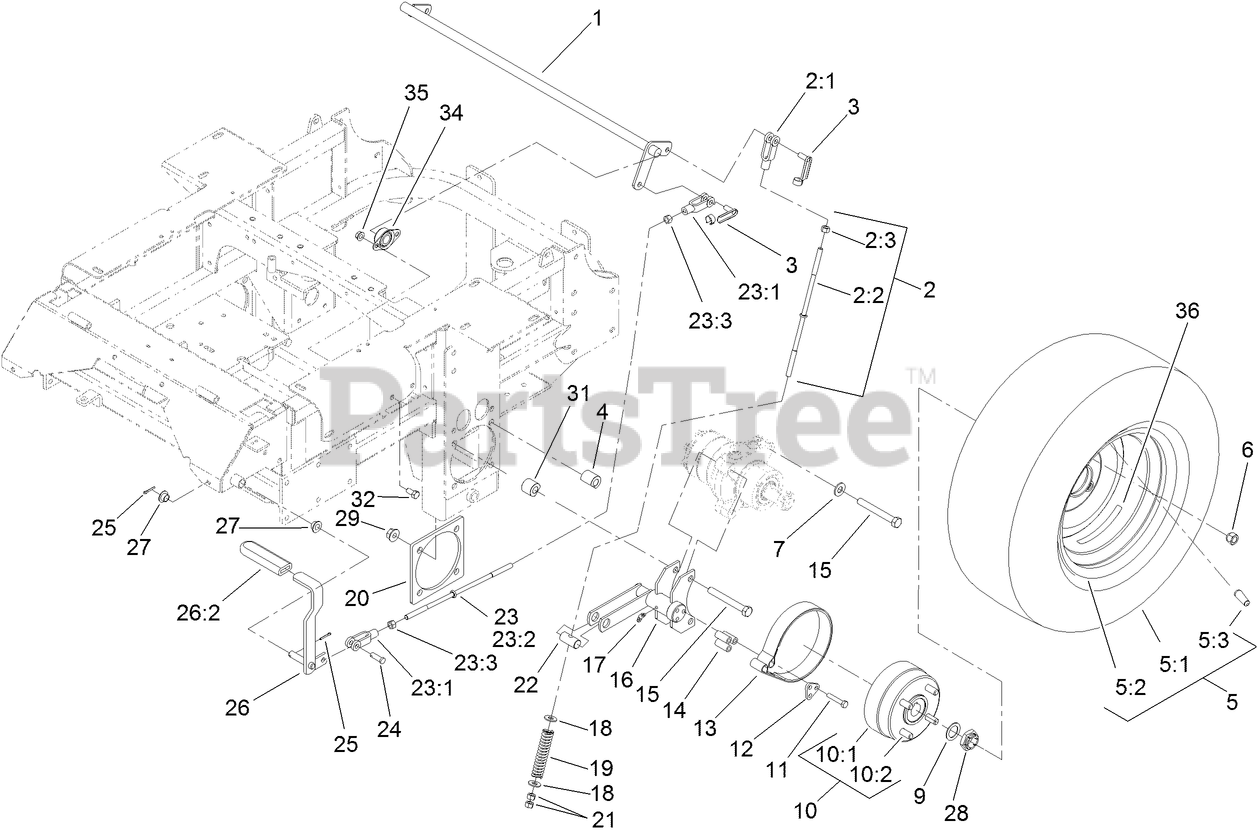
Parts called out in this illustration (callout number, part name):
1	SHAFT-BRAKE
2	BRAKE ROD ASM
2:1	YOKE-LINKAGE, BRAKE
2:2	ROD-BRAKE
2:3	NUT-HEX
3	PIN-SPRING, CLEVIS
4	SPACER-WHEEL, LONG
5	WHEEL AND TIRE ASM
5:1	TIRE
6	NUT-LUG
7	WASHER-THRUST
9	WASHER-SPACER
10	WHEEL HUB ASM
10:1	HUB-WHEEL
10:2	STUD-WHEEL
11	SCREW-HH
12	RETAINER-BAND, BRAKE
13	BAND-BRAKE
14	SPACER
15	SCREW-HH
16	BRACKET-BRAKE
17	FITTING-GREASE
18	WASHER-FLAT
19	SPRING-BRAKE
20	PLATE-REINFORCEMENT
21	NUT-HEX
22	PIN-TRUNION
23	BRAKE ROD ASM
23:1	YOKE-LINKAGE, BRAKE
23:2	ROD-BRAKE
23:3	NUT-HEX
24	PIN-CLEVIS
25	PIN-COTTER
26	BRAKE LEVER ASM
26:2	GRIP-LEVER
27	BEARING-CONTROL
28	LOCKNUT
29	NUT-HHF
31	SPACER-WHEEL, SHORT
32	SCREW-HH
34	BEARING-FLANGE, SIDE
35	NUT-HHF, WHIZ
36	DECAL-TORQUE, WHEEL HUB LUG
